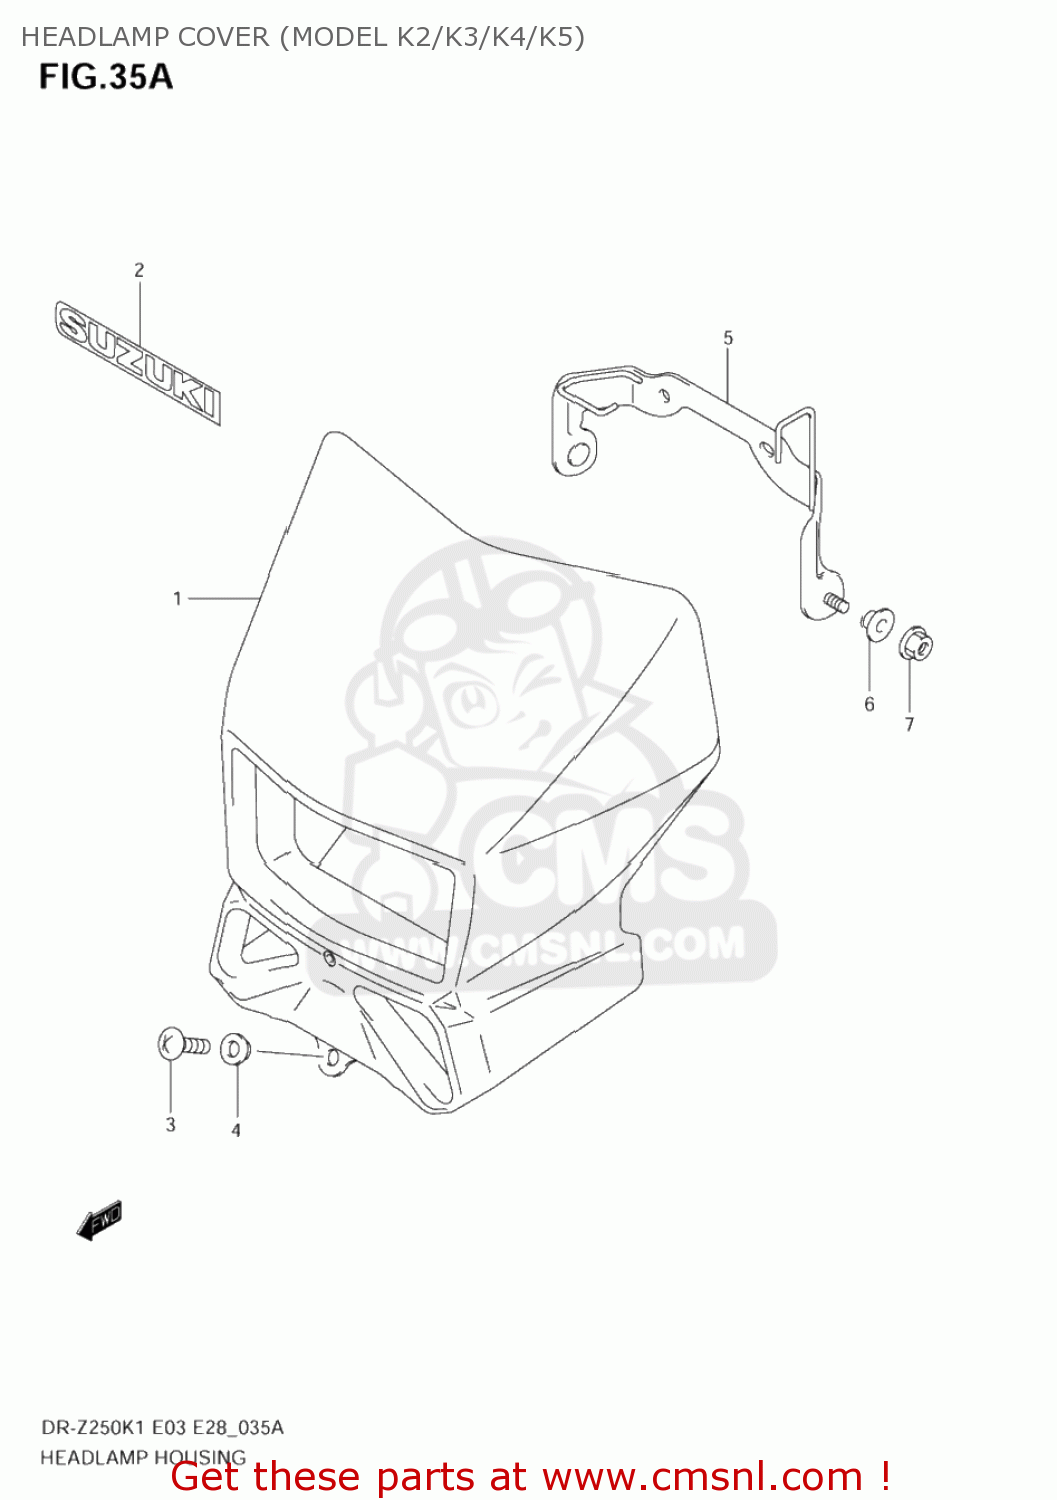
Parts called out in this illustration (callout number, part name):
1	COVER, HEADLAMP (WHITE)
2	EMBLEM,SUZUKI
3	SCREW(5X12)
4	WASHER
5	BRACKET,HEADLAMP COVER
6	WASHER
7	NUT
